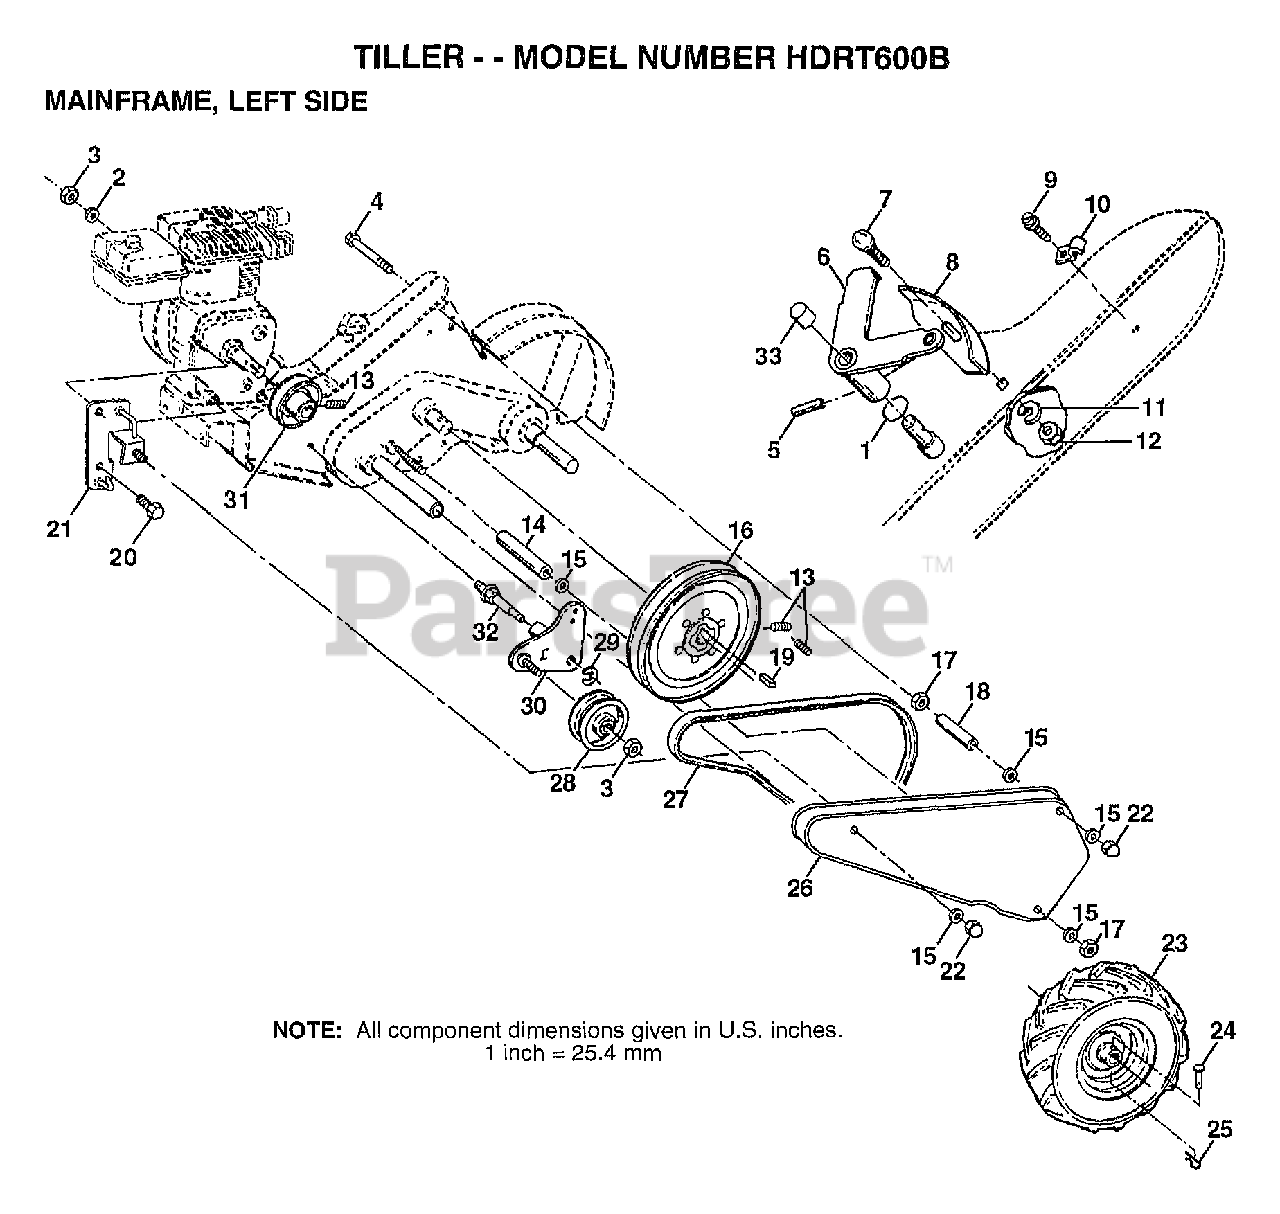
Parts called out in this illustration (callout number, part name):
1	O-RING TI
2	LOCKWASHER
3	NUT.HEX.3/8-16UNC
4	BOLT TI
6	LEVER ASM CRT
7	BOLT
8	PANEL TI
10	CONDIUT CLIP T
11	LOCKWASHER
13	SET SCREW
14	SPACER TI
15	WASHER
16	"SHEAVE 10"" CRT"
17	NUT.HEX.5/16-18
18	SPACER TI
19	KEY T
20	BOLT.FIN.HX.5/16
21	BRKT ASSY TI
22	NUT TI
23	TIRE TI
23	RIM.16X4X8.WHT
24	RIVET.PAN HD.1.75
25	SPRING.RETAINER
26	GUARD.BELT.MS-550
27	BELT.DRIVE
29	KLIP RING
31	ENGINE SHEAVE
32	SHAFT.IDLER
33	CAP PLUNGER BLACK
